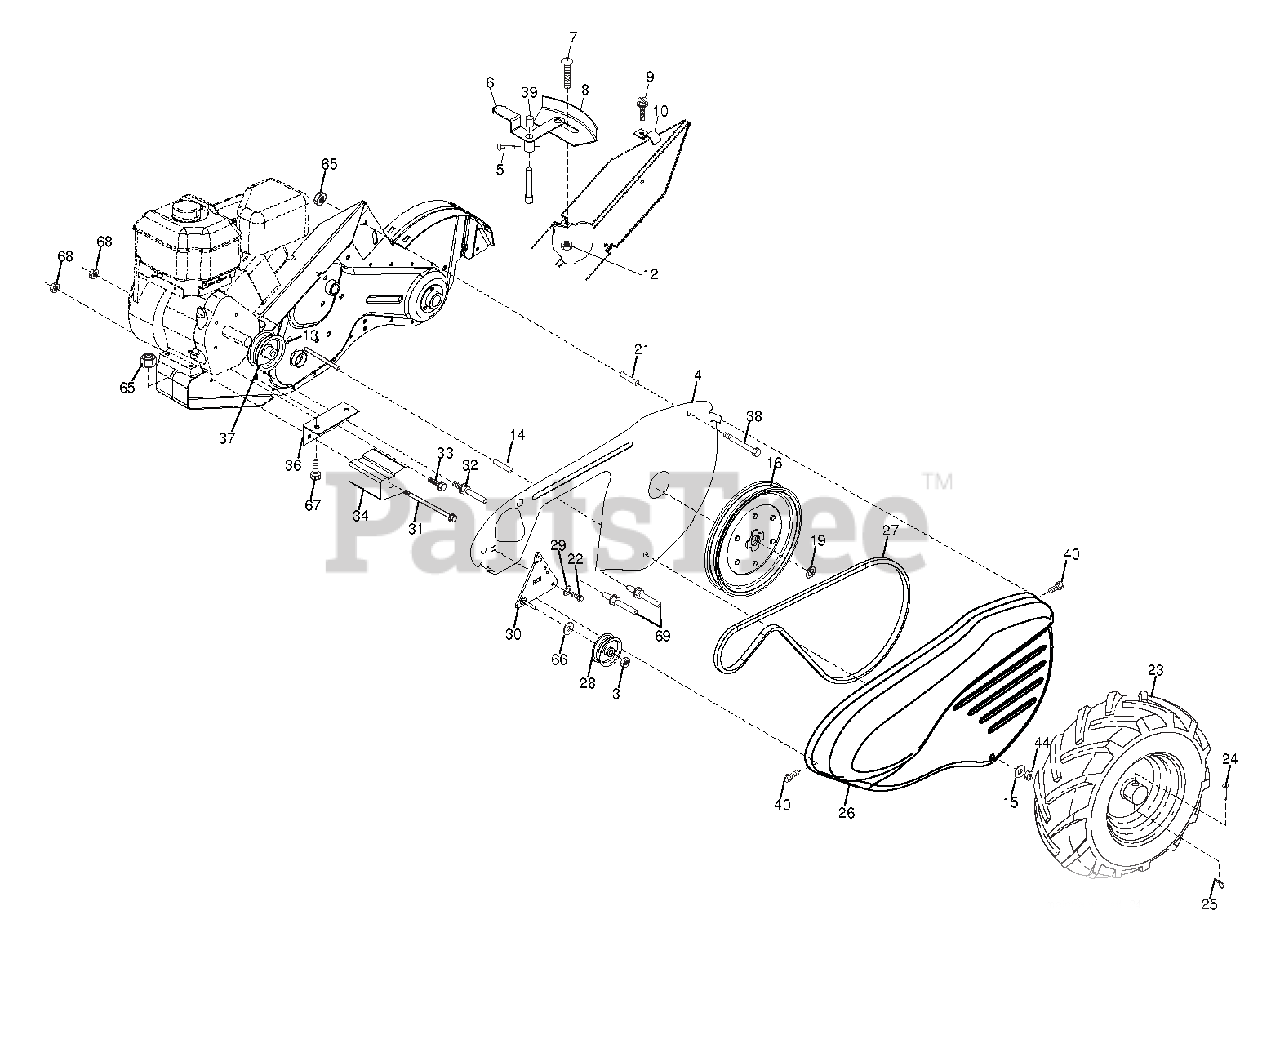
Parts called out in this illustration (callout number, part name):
3	Nut, Hex 3/8-16
4	Shield, Inner Belt Guard
5	Pin, Shift Lever
6	Lever, Shift
7	Bolt 1/4-20 unc x 1/2 Gr. 5
8	Plate, Shift Indicator
9	Screw, Tap Hex Head
10	Clip, Cable
12	Nut, Keps Hex 1/4-20 unc
13	Screw Set 5/16-18 x 3/8 Patch
14	Spacer, Split .327 x .42 x 2.0
15	Washer 11/32 x 11/16 x 16 Ga.
16	Sheave, Transmission
19	Ring, Retainer
21	Spacer, Split .327 x .42 x 1.2
22	Bolt, Hex Head 5/16-24 unf x 1
24	Rivet, Drilled
25	Retainer Spring
26	Guard, Belt
27	Belt, V
28	Pulley, Idler
29	Ring, Klip
30	Bracket, Idler
31	Bolt, Hex 5/16-16 x 12
32	Shaft, Idler Arm
33	Bolt, Hex 3/8-16 x 1
34	Counterweight, LH
36	Bracket, Reinforcement, LH
37	Sheave, Engine
38	Bolt, Fin Hex 5/16-18 x 2-3/4
39	Cap, Plunger
40	Screw Hex Wsh Hd #8-18 x 1/2
44	Locknut, Washer Insert 5/16-18
65	Nut, Hex, Flangelock
66	Washer 13/32 x 13/16 x 12 Ga.
67	Bolt, Hex Head, Gr. 25/16-18 x
68	Nut Keps Hex 3/8-16 unc
69	Keeper Belt Engine
